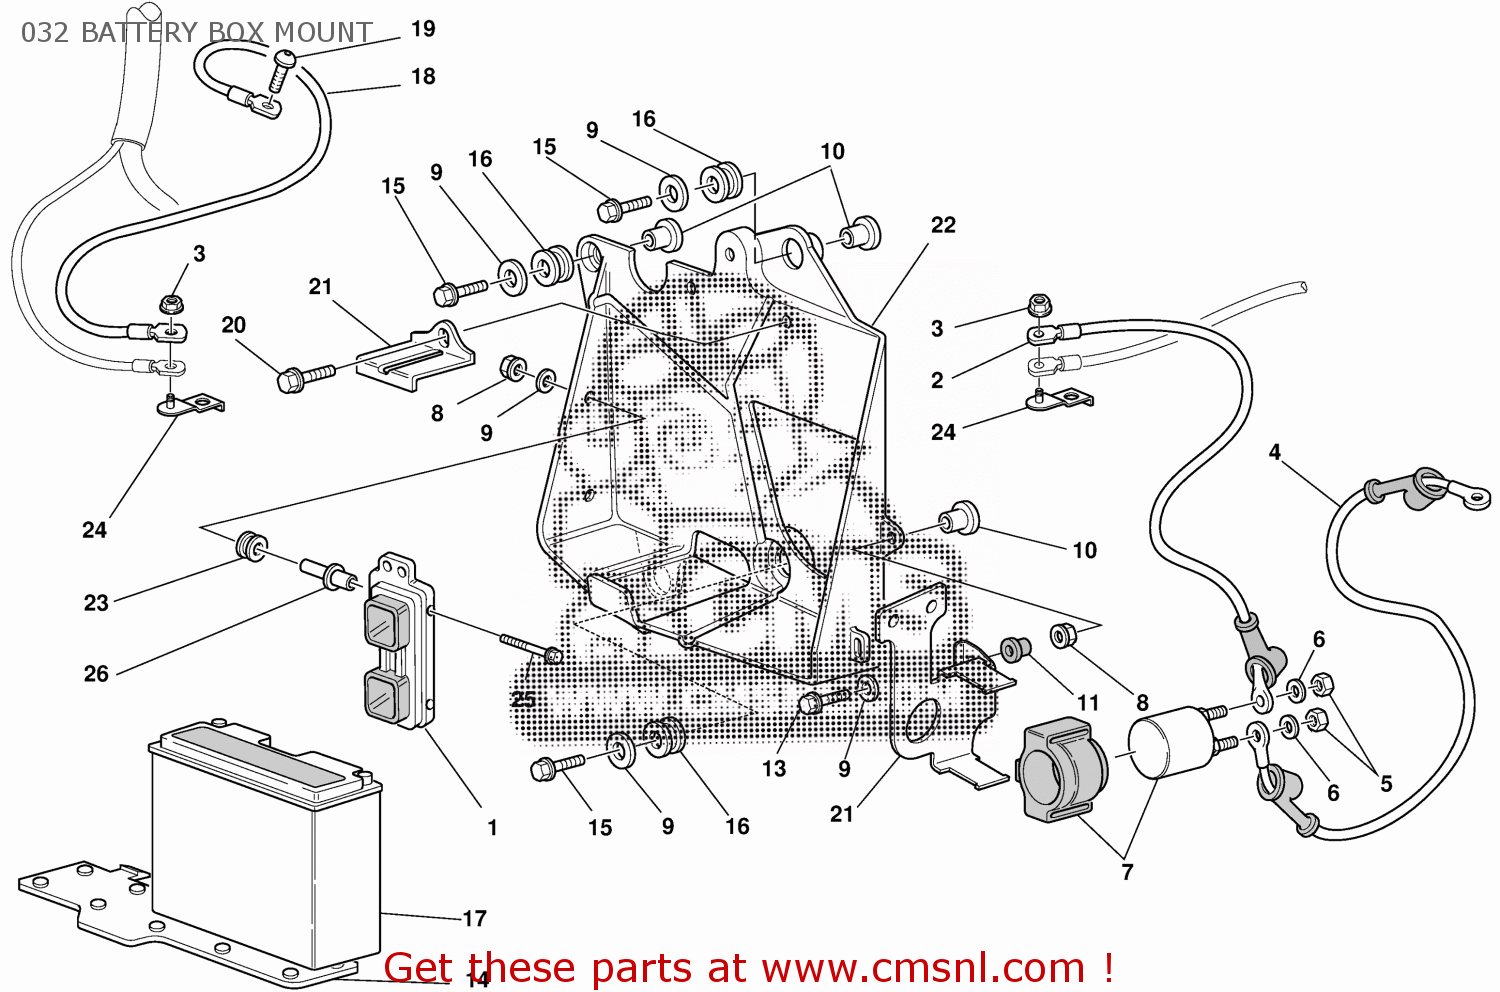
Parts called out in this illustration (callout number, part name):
1	ENGINE CONTROL UNIT
2	CABLE
3	NUT
4	WIRE STARTER MOTOR
5	NUT
6	SPRING WASHER 6MM DIN137B
7	STARTER RELAY
8	SELF LOCKING NUT M6 H5.5
9	WASHER 16X6.4X1.5
10	SPACER
11	SPACER
12	PLATE
13	SCREW
14	RUBBER PAD
15	SCREW M6X20
16	RUBBER PAD
17	BATTERY ASSY (YT12B-4)
18	CABLE
19	SPECIAL SCREW M8X10
20	SCREW M6X10
21	BRACKET, MAGNETIC SWITCH
22	BATTERY HOLDER
23	VIBRATION DAMPER PAD
24	PLATE
25	SCREW M6X60
26	SPACER
